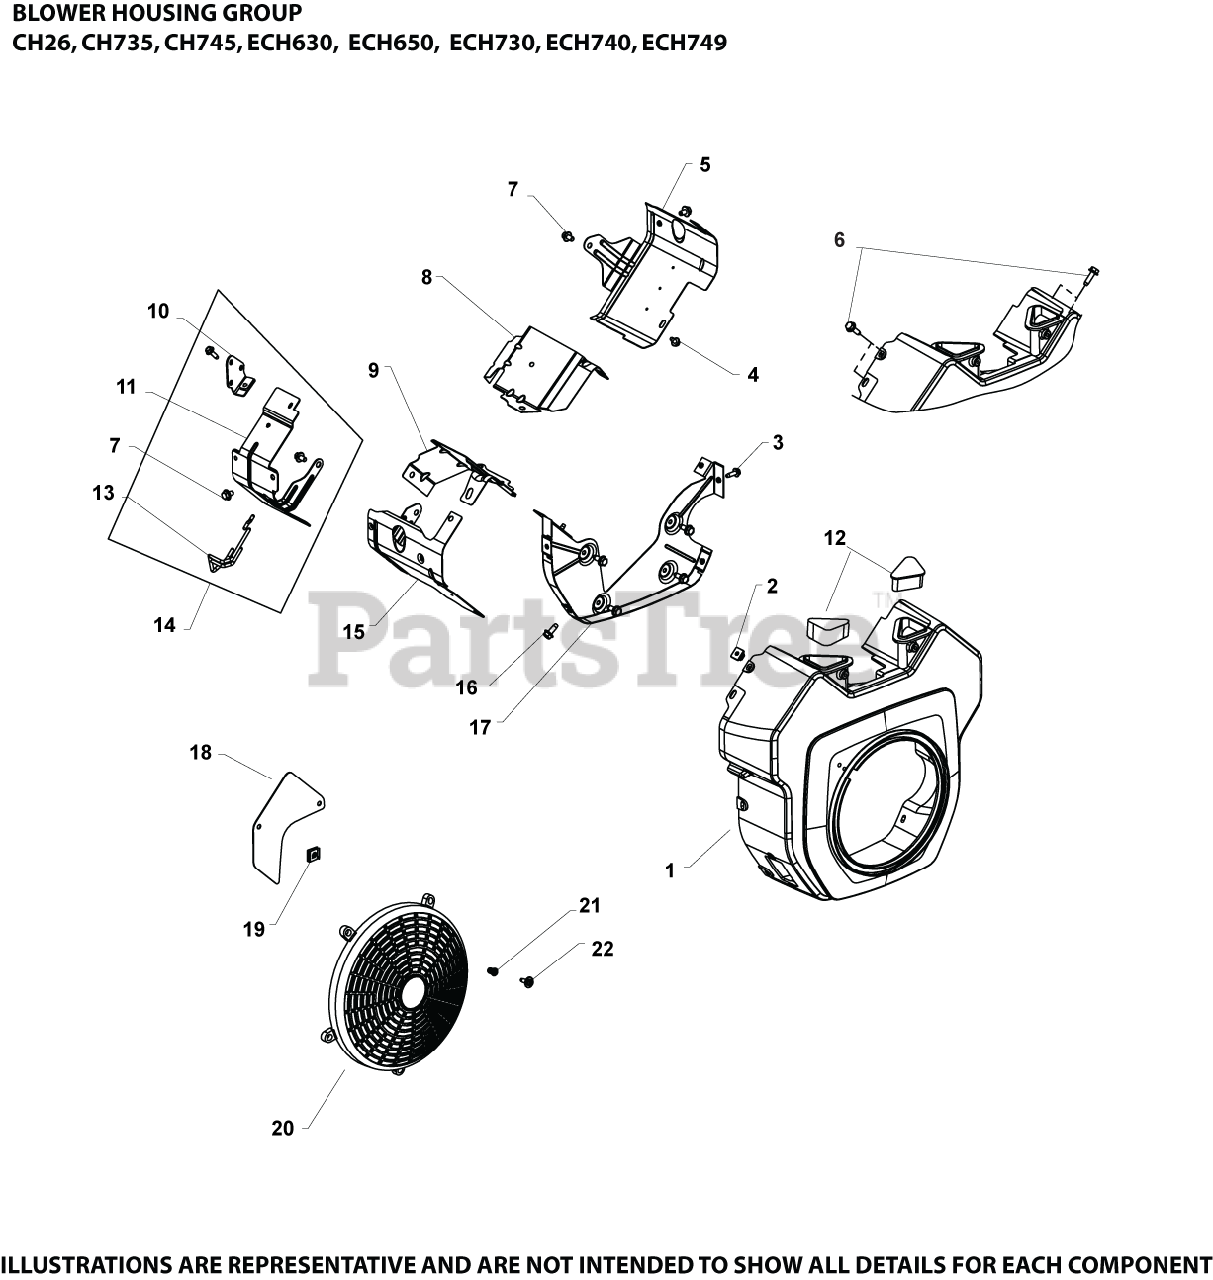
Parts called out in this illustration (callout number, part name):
1	HOUSING, BLOWER
2	NUT, PLASTIC - BLACK
3	SCREW, THREAD FORMING
4	SCREW, THREAD FORMING
5	BAFFLE, BARREL
6	SCREW, THREAD FORMING
7	SCREW, THREAD FORMING
8	BAFFLE, VALLEY #1 CYLINDER
9	BAFFLE, VALLEY #2 CYLINDER
12	COVER, BLOWER HOUSING USE 24 096 160-S
15	BARREL, LEFT BAFFLE-(#24063112S)
16	SCREW, THREAD FORMING
17	PLATE, BACKING
18	KIT, ACCESS PANEL
19	CLIP, BAFFLE MOUNTING USE 25 154 37-S
